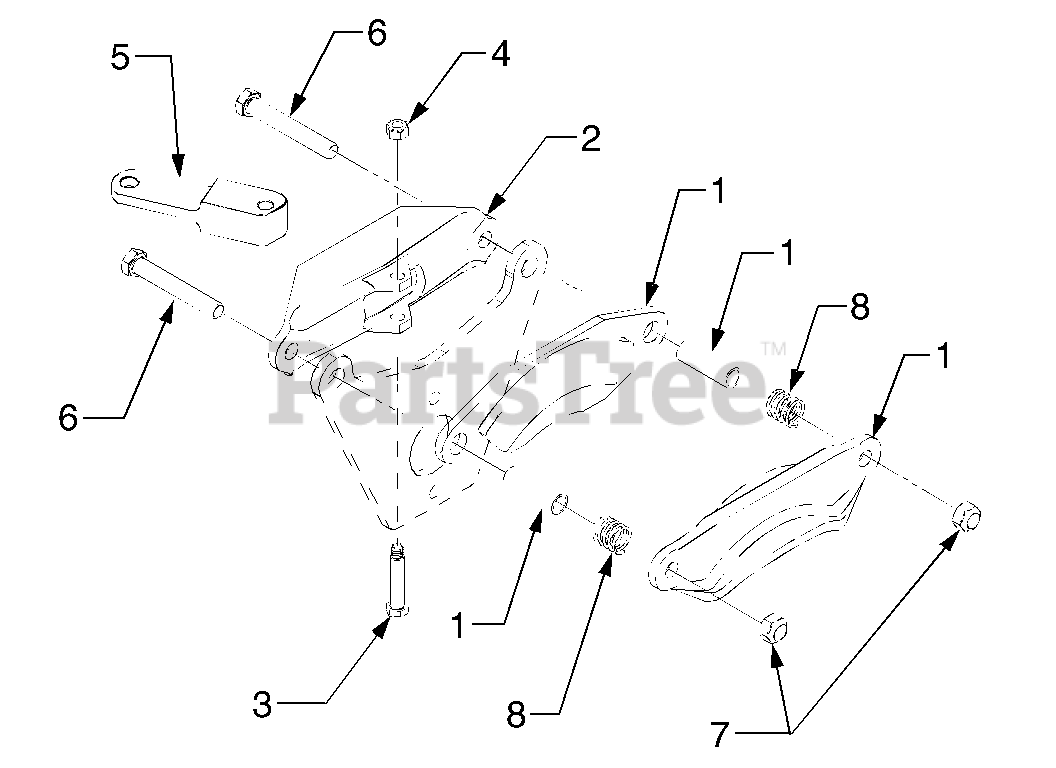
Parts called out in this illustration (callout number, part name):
1	KIT-BRAKE PUCK SVC
2	Bracket, Brake Actuator
3	Screw, Shoulder
4	Nut, Hex Top Lock, 1/4-20
5	Arm, Brake Actuator
6	Screw, Hex Cap, 3/8-24 x 2.5 GR5 4
7	Nut, Hex Lock, 3/8-24
8	Spring, Compression
